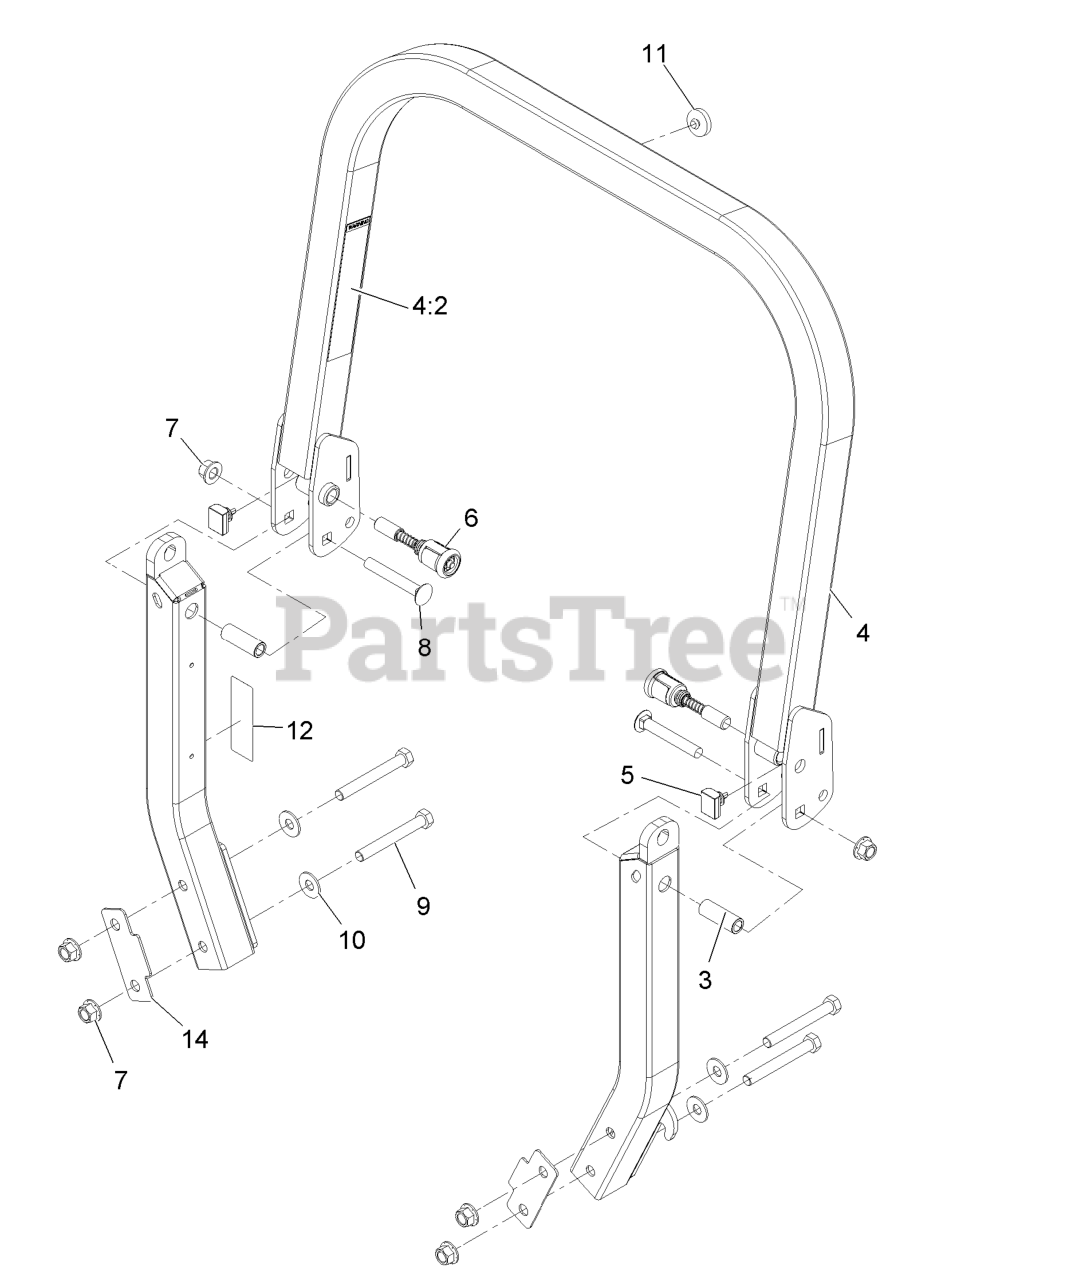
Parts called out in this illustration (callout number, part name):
4	UPPER ROPS ASM
4:2	DECAL-WARNING, FOLDING RO
5	BUMPER-ROPS
6	PIN-SPRING
7	Nut-Lock 1/2-13
8	SCREW-CARR
9	SCREW-HH
10	WASHER-SPRING
11	BUMPER-PUSH-IN, RUBBER
12	DECAL-CAUTION
